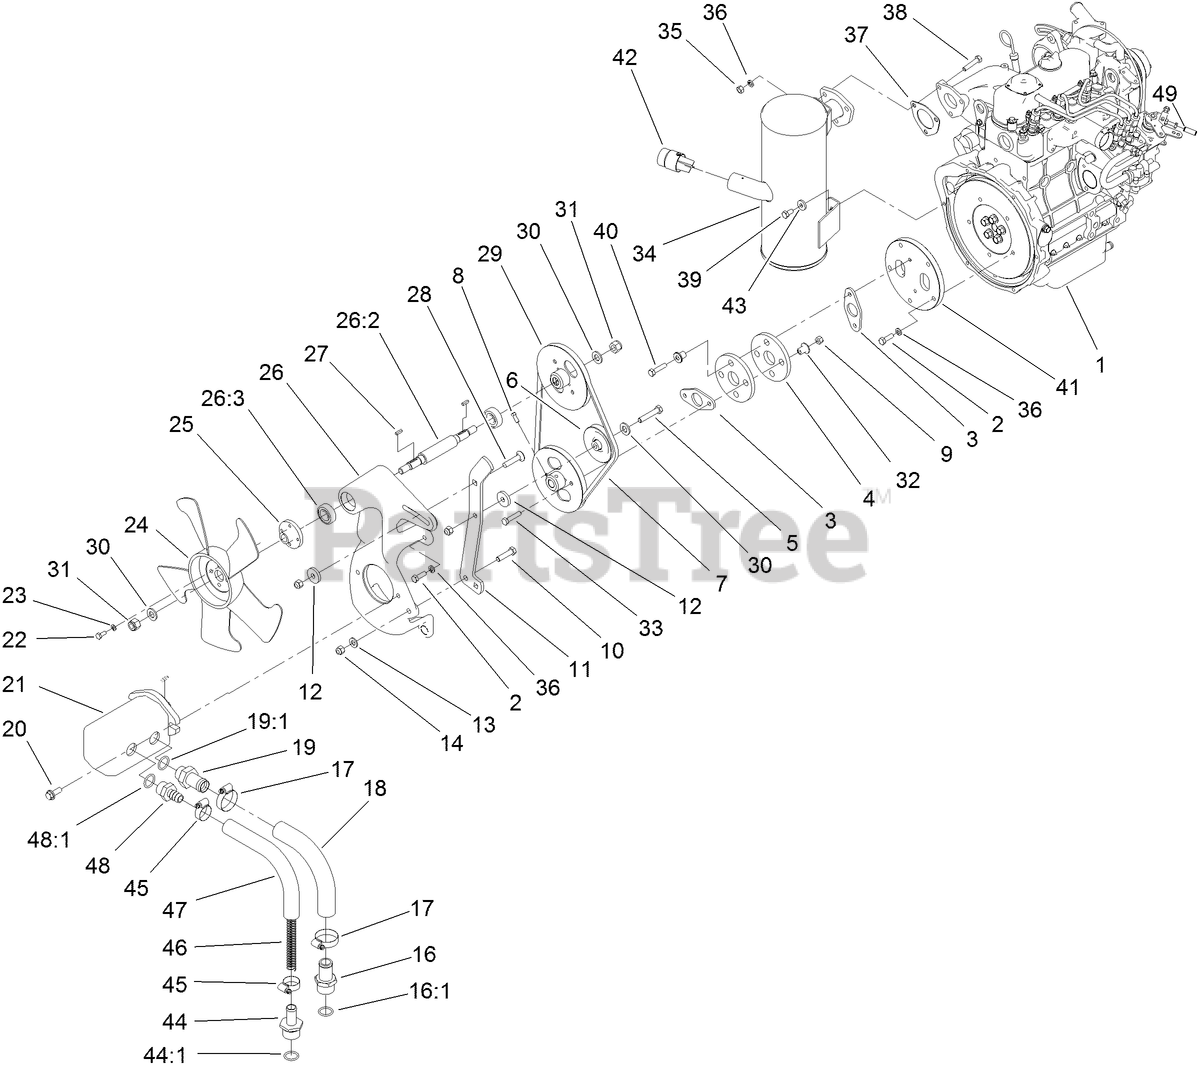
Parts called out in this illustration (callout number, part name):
1	ENGINE ASM
3	SPACER-COUPLER
4	COUPLING-RUBBER
5	SCREW-HH
6	PULLEY-IDLER
7	V-BELT
8	SCREW-SET
9	NUT-LOCK
10	SCREW-HH
11	ARM-TENSIONER
12	SPACER
13	WASHER-FLAT
14	NUT-LOCK, NI
16	FITTING-STR
16:1	O-RING
18	HOSE-SUCTION, FORMED
19	FITTING
19:1	O-RING
20	SCREW-HHF
21	HYD PUMP ASM
22	SCREW-HH
23	WASHER-LOCK
25	ADAPTER-FAN
26	PUMP MOUNT ASM
26:2	SHAFT-FAN
26:3	BEARING-BALL
27	KEY-SQUARE
28	SCREW-CARR
29	PULLEY-KEYED
30	WASHER-FLAT
31	NUT-LOCK
32	SPACER
33	SCREW-HH
34	MUFFLER
35	NUT-HEX
36	WASHER-LOCK
37	GASKET-MUFFLER
38	SCREW-HH
39	BOLT
41	ADAPTER-FLYWHEEL
42	SCREEN-ARRESTER, SPARK
43	WASHER-FLAT
44	FITTING-HOSE, BARBED
44:1	O-RING
45	CLAMP-HOSE
46	Spring-Compression
47	HOSE-SUCTION, HYD
48	FITTING-STRAIGHT
48:1	O-RING
49	TUBE-ALUMINUM
